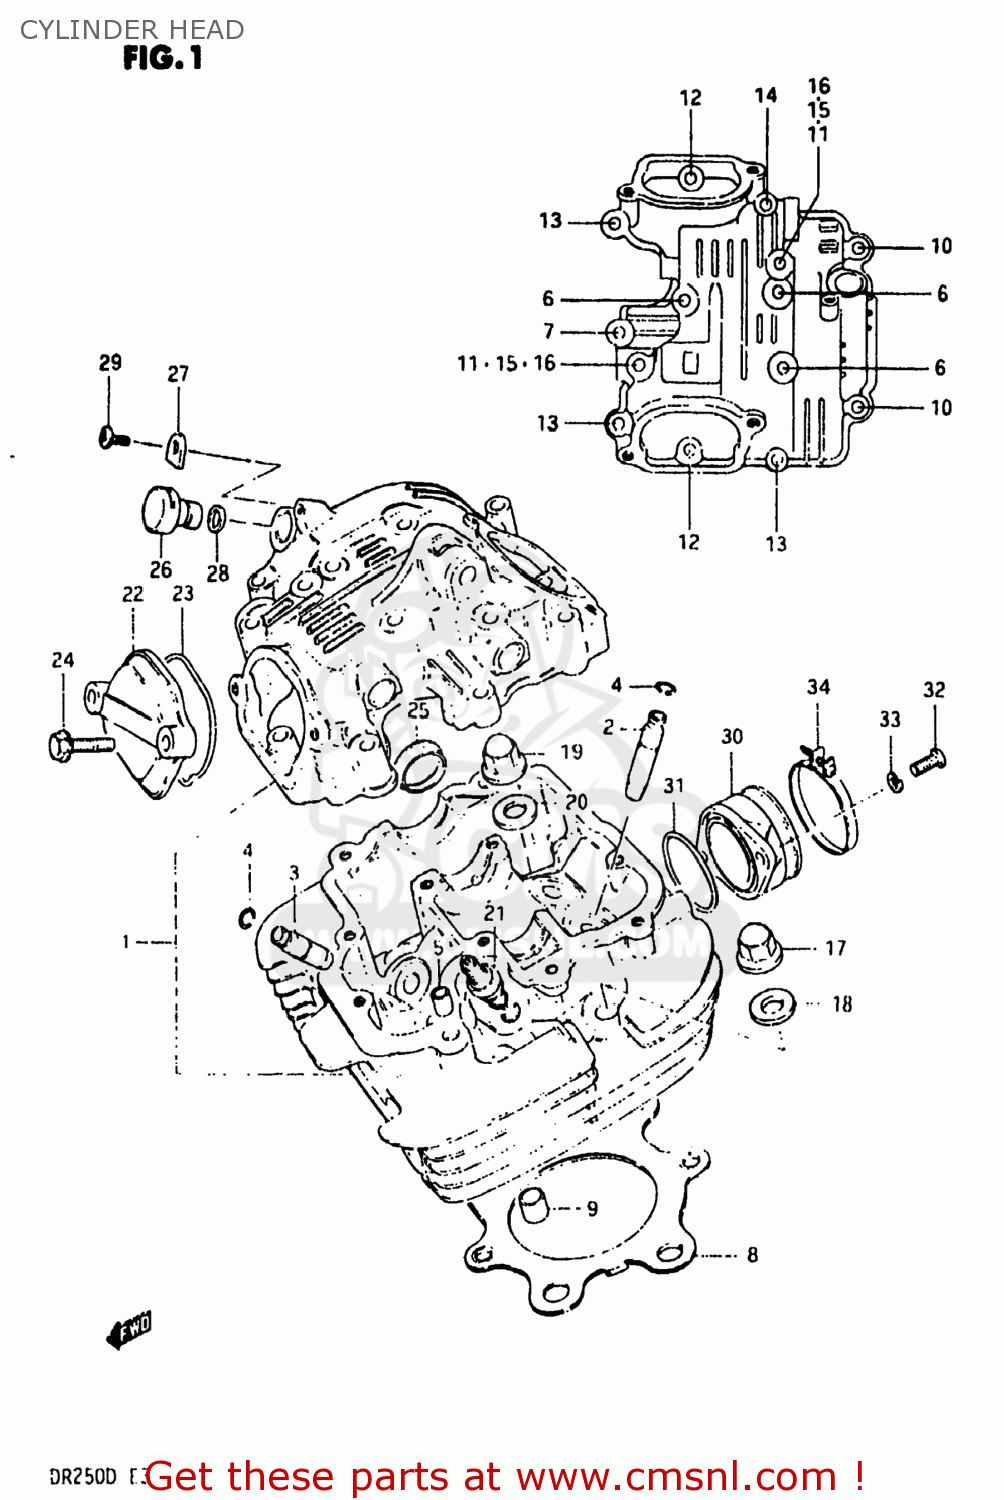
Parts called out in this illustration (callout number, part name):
1	HEAD ASSEMBLY,CYLINDER
2	GUIDE,INTAKE VALVE
3	GUIDE,VALVE
4	RING,SNAP
5	PIN(6.2X8X11)
6	BOLT ,6X60
7	BOLT 6X30
8	GASKET,CYLINDER HEAD (NAS)
9	PIN
10	BOLT
11	BOLT (6X30)
12	BOLT 6X30
13	BOLT (6X45)
14	BOLT ,6X60
15	NUT
16	GASKET (NAS)
17	NUT
18	WASHER (10.5X22X2.3)
19	NUT
20	GASKET(10.5X22X2) (NAS)
21	SPARK PLUG D8EA
22	CAP,INSPECTION
23	O RING(D:2.4,ID:23)
24	BOLT
25	PLUG(OD:30)
26	PLUG,TACH GEAR SLEEVE HOLE
27	PLATE,TACH DRIVE GEAR SLEEVE
28	SEAL,TACHOMETER DRIVEN
29	SCREW(5X12)
30	PIPE,INTAKE
31	O-RING (D:2.4 ID:39.7)
32	SCREW
33	LOCK WASHER
34	CLAMP
